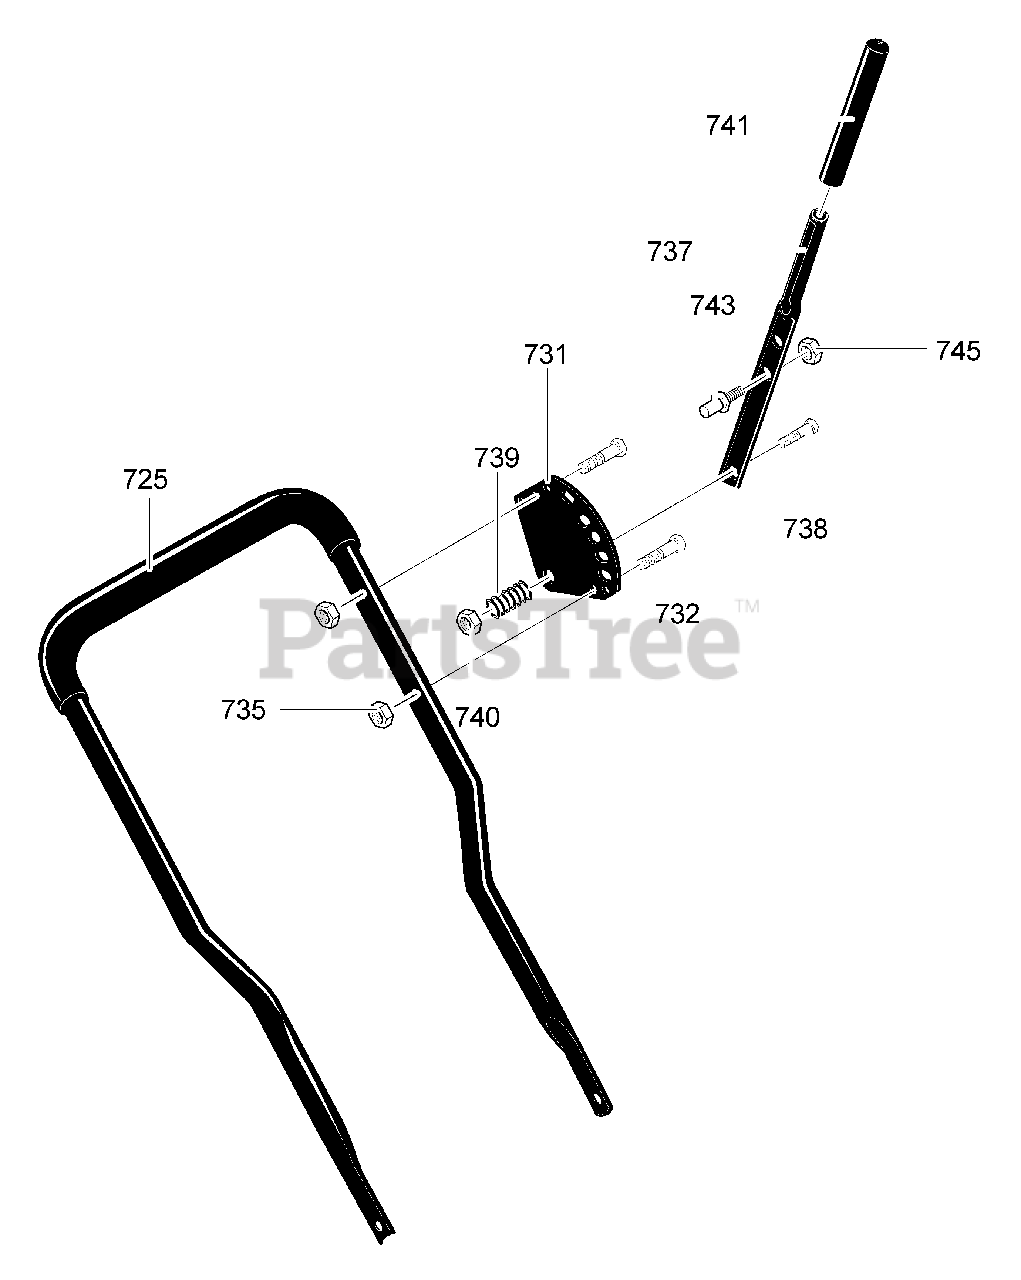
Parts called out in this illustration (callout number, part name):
725	Upper Handle & Foam
731	Selector Plate
732	Screw, 1/4-20x1.25
735	Nut, 1/4-20
737	Depth Adjust Handle
738	Screw, 5/16-18x1.25
739	Spring, Compression
740	Nut, 5/16-18
741	Grip, Hand
745	Nut, 3/8-16
